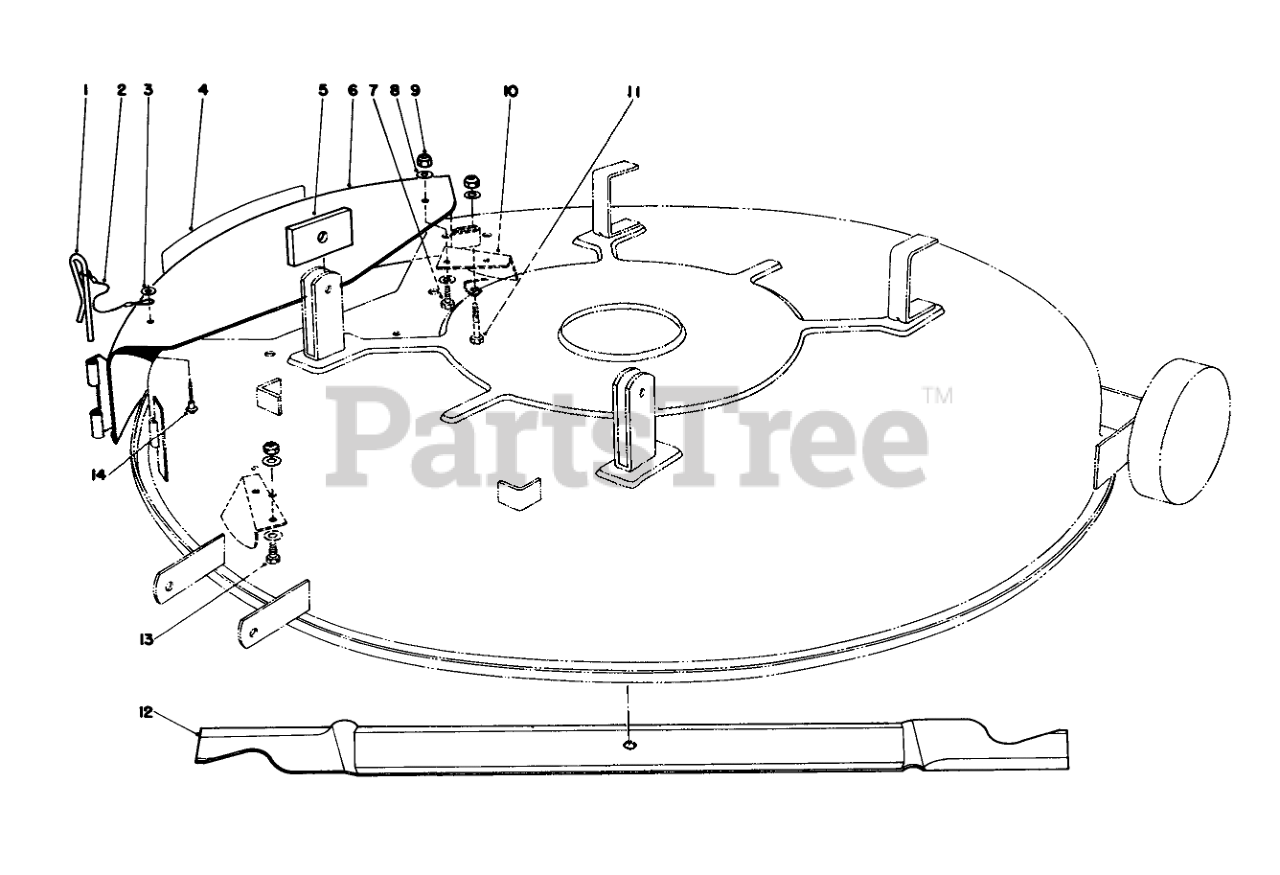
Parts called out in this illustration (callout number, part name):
1	PIN-LOCKING, CHUTE
2	LANYARD
3	WASHER-PLAIN
4	COVER DECAL
5	SPACER
6	Cover-Mulcher Assembly (Incl. Ref. #1-4 & 14)
7	SCREW-HH
8	WASHER-PLAIN
9	NUT-LOCK, NI
10	KICKER B
11	SCREW-HH
12	Blade
13	SCREW-HH
14	RIVET-BLIND
